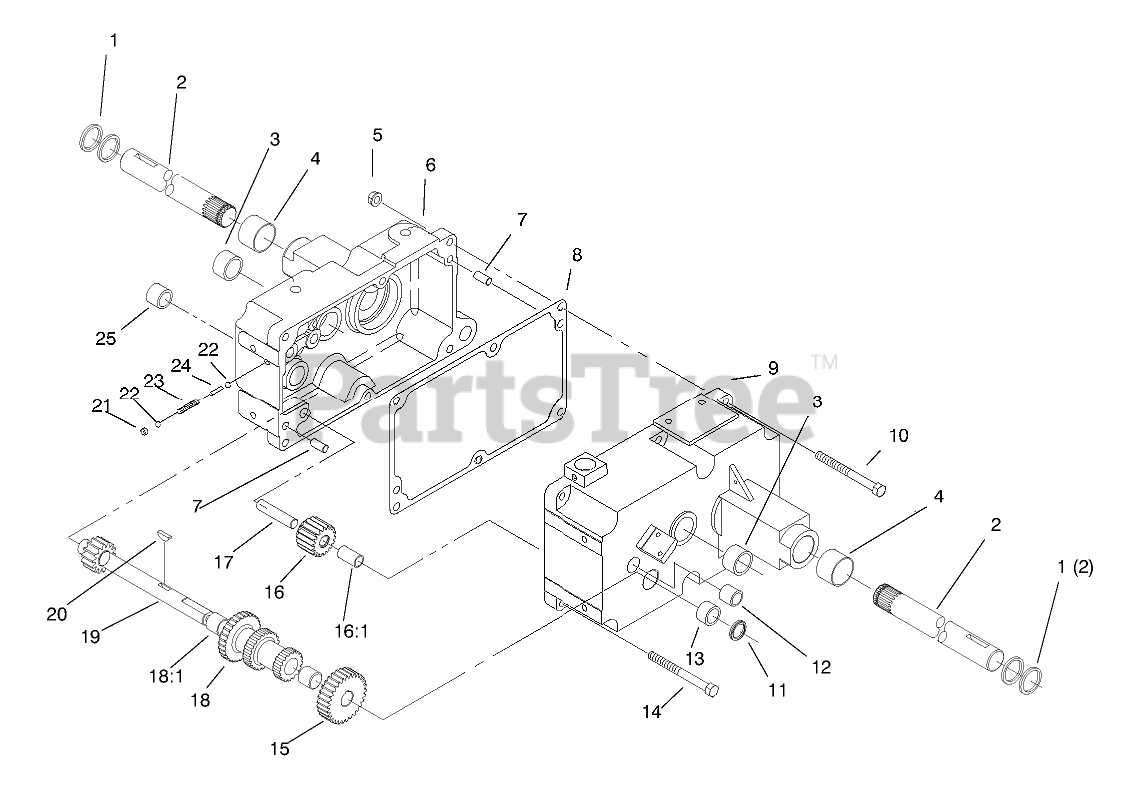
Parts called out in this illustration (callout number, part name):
1	SEAL-OIL
2	AXLE-REAR
3	BEARING-NEEDLE
4	BEARING
5	NUT-LOCK, NI
6	CASE-RH TRANS
7	PIN-DOWEL
8	GASKET-TRANSMISSION
9	CASE-TRANS LH
10	SCREW-HH
11	SEAL-OIL
12	BEARING-NEEDLE
13	BEARING-NEEDLE
14	SCREW-HH
15	GEAR-CLUSTER SHAFT
16	GEAR/BUSHING ASM-REVERSE IDLER
17	PIN-DIFFERENTIAL
18	GEAR-CLUSTER
19	SHAFT-CLUSTER
21	CUP-PLUG
22	BALL-DETENT
23	SPRING-SHIFT STOP
24	PIN-SHIFT
25	BEARING-NEEDLE
25:1	Shift Lever
25:2	Shaft-Lever
